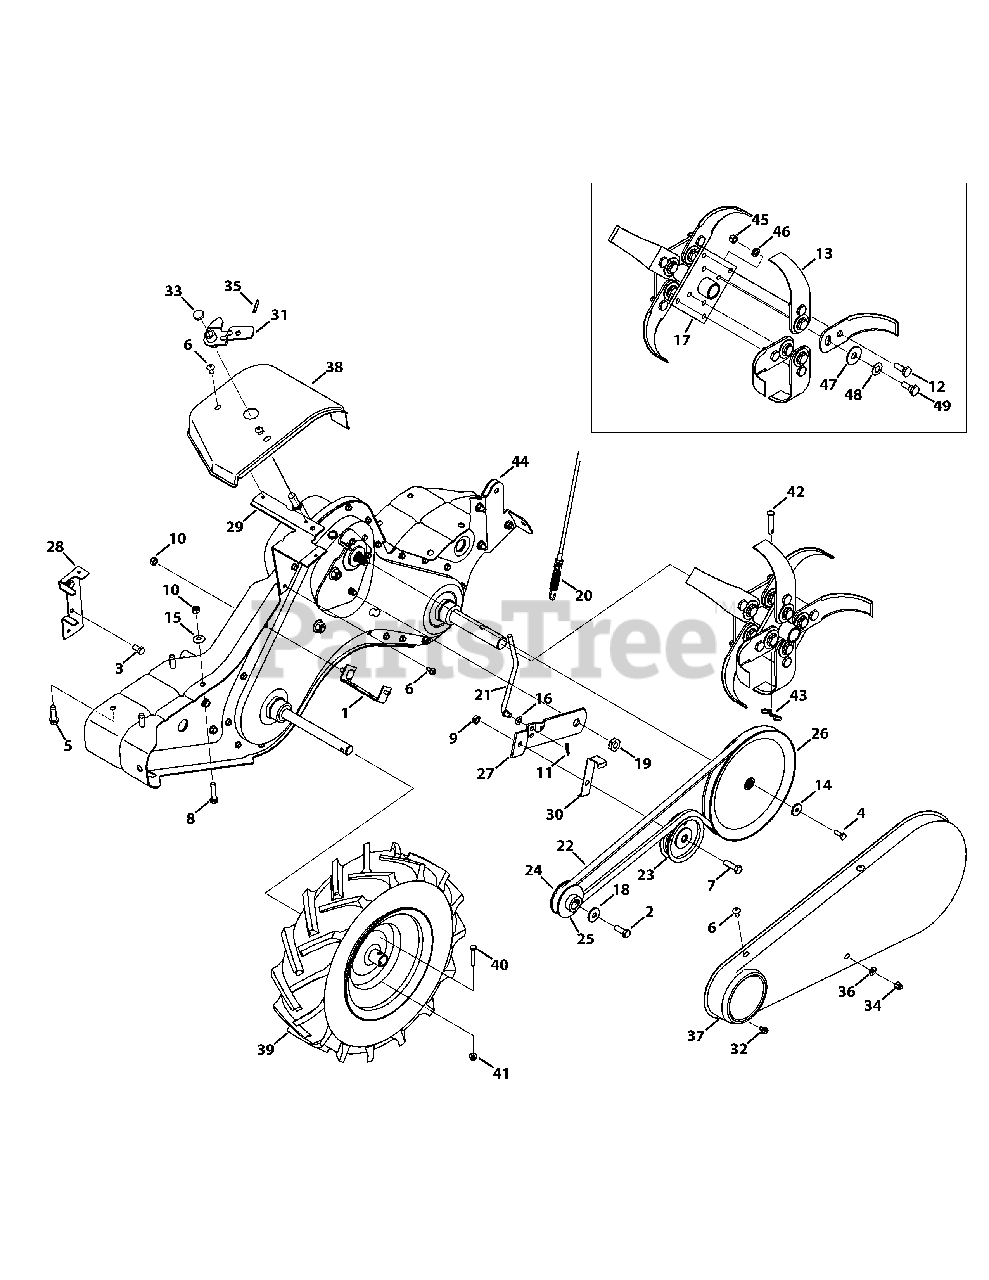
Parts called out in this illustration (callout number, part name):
1	Belt Cover Bracket Assembly
2	Hex Head Screw, 3/8-24 x 1.00
3	Hex Bolt, 5/16-24 x .625
4	Hex Bolt, 1/4-28 x .75"
5	Screw, 3/8-16 x 1.250
6	Hex Washer Screw
7	Hex Head Screw, 3/8-16 x 1.25
8	Hex Head Screw, 5/16-18 x 1.50
9	Jamlock Nut, 3/8-16
10	Flangelock Nut, 5/16-18
11	Cotter Pin, .072 DIA. x 1.13 LG
12	Screw, Shoulder, 3/8-24 x 1/2 x .180
13	Articulating Tine
14	Washer, Flat, .265 x .938 x .120
15	Washer, Bell, .340 x .872 x .060
16	Washer, Spring, .317 x .625 x .020
17	Tine Adaptor Assembly
17	Tine Assembly
18	Washer, Bell, .396 x 1.140 x .095
19	Shoulder Nut, 7/16-20
20	Clutch Cable
21	Idler Pulley Rod
22	Belt, 4L x 58.16 LG
23	Flat Idler Pulley w/ Flanges, 3.75 O.D.
24	Engine Pulley, Inner Half
25	Engine Pulley, Outer Half
26	Input Pulley, 4L x 8.594
27	Idler Pulley Bracket
28	Belt Keeper Bracket, B&S 6.5 HP
29	Shift Cover Bracket
30	Idler Belt Keeper
31	Shift Crank Assembly
32	Screw, 1/4-20:0.375
34	Lock Nut, Cap, 1/4-28
35	Spiral Pin, 3/16 x 1.00
36	Washer, Flat, .271x .630 x .065
37	Belt Cover
38	Shift Cover
39	Wheel, 16 x 4.6 x 8
40	Hex Head Screw, 1/4-20 x 1.50
41	Flangelock Nut, 1/4-20
42	Clevis Pin, .375 x 1.75
43	Cotter Pin, Bow-Tie
44	Complete Gear Case Assembly
45	Hexlock Nut, 3/8-24
46	Washer, Lock, 3/8
47	Washer, Flat, .51 x 1.5 x 0.07
48	Washer, Bell, .525 x 1.00 x .050
49	Screw, Shoulder, 3/8-24 x 1/2 x .325
